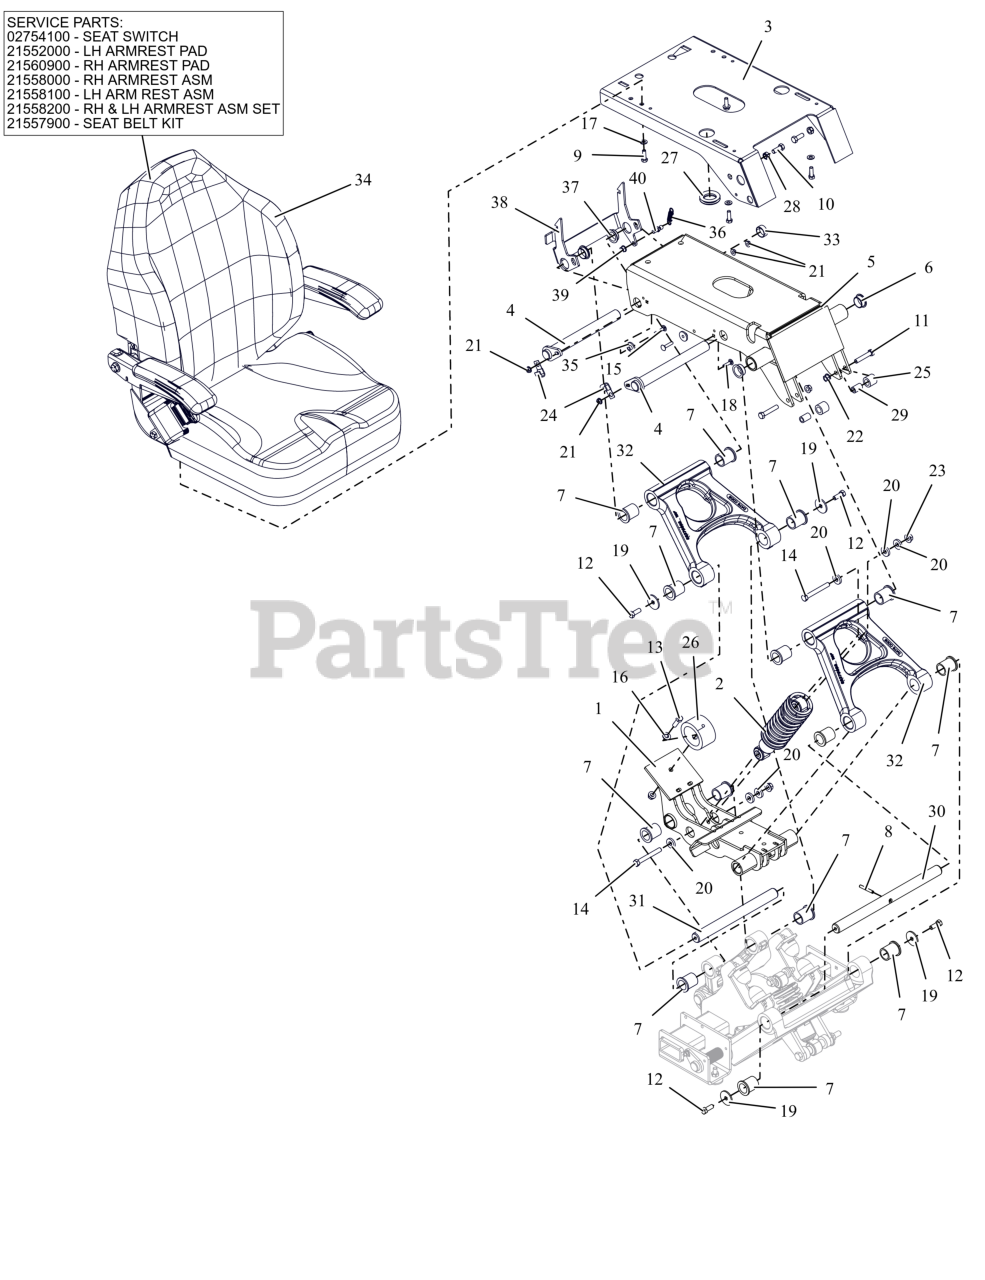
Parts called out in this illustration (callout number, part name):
1	WLDMT, SUSPENSION MID LINK
2	SHOCK, UPPER - TENNECO
3	WLDMT- SEAT MOUNT - RED
4	WLDMT, UPPER PIVOT SHAFT (RED)
5	WLDMT, SEAT MOUNTING SUPPORT (RED) W/ SAFETY DECALS
6	BSHG-FLG 1.0X1.125X.50X1.375 R
7	BEARING, SINTERED BRONZE FLANGE
8	PIN-ROLL .250X1.75
9	BLT,HEX .31-18X1.00 G5 ZCC
10	BLT,HEX .38-16X1.00 G5 ZCC
11	BLT,HEX .38-16X2.00 G5 ZCC
12	BLT, HEX .38-16X1.00 G8ZCCEP30
13	BLT, HEX .38-16X1.25 G5 ZCC
14	BLT,HEX M10-1.5X80 G10.9 ZCC
15	BTL,RHSN .250-20 X 1.25 G5 ZCC
16	WSHR,FLT .406X.812X.065 ZCC
17	WSHR,FLT .344X.688X.065 ZCC
18	BLT, RHSN .25-20X1.00 G5 ZCC
19	WSHR, FLT .380X1.50X.125 ZCC
20	WSHR, FLT .406X1.00X.188 ZCC
21	NUT-LK-CTR-FLG .25-20 ZC120
22	NUT-LK-CTR-FLG .375-16 GF ZCC
23	NUT, FLG-CTR LK M10-1.50 ZCC
25	BUMPER,RUBBER .62X1.0X.88 LG
26	BUMPER, RADIAL (GBR)
27	GROMMET 1.25ID X 1.5OD
28	NUT, WELD .375-16 HEX
29	BUSH.,S.391X.622X.950 ST
30	SHAFT, PIVOT
31	SHAFT, PIVOT
32	MACHINED, UPPER LINK
33	CAP, 1.000 ID X .375 DEEP
34	SEAT, PT600
34	SWITCH- SNAP MTG N.O.
34	PAD, ARMREST LH
34	PAD, ARMREST RH OR LH (HARD)
34	ARMREST, RH ASSEMBLY
34	ARMREST, LH ASSEMBLY
34	SET, RH & LH ARMREST ASSEMBLY
34	KIT, SEAT BELT
35	BSHG-FLG .265X.448X.375X1.00
36	SG-TENS .06X.46X2.00
37	BSHG, FLANGE 1.000x1.125x.375x1.375
38	BRKT, SEAT LATCH (BLACK)
39	NUT,LK-CTR-FLG .31-18 GF ZCC
40	STUD- BALL
